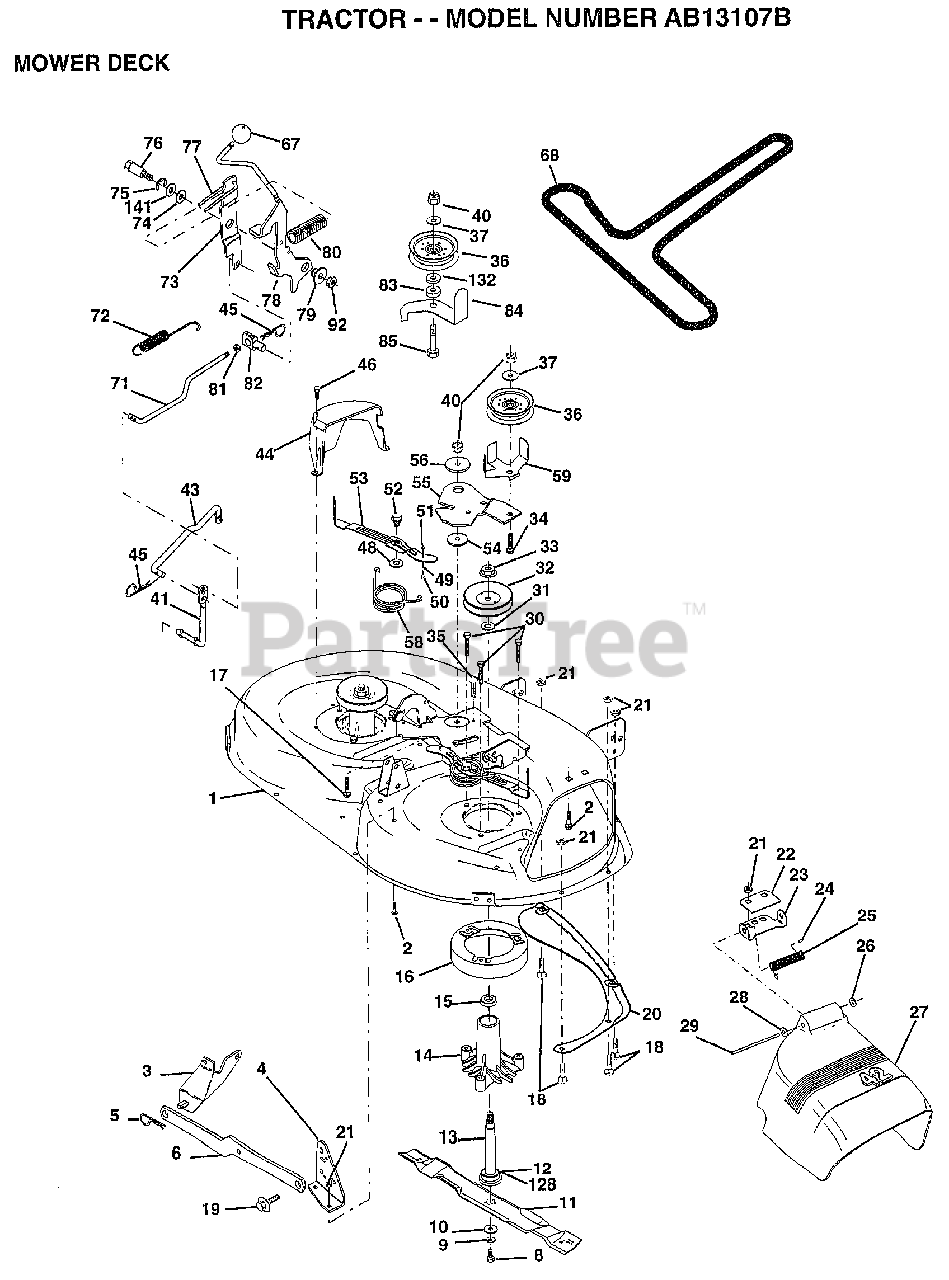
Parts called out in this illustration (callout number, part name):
1	"HOUSING ASSY.42"""
2	BOLT
3	BRKT ASM SWAY BAR
4	BRKT DECK SW BAR
8	BLADE BOLT
10	WASHER.HARD.BLADE
11	"BLADE.42"" HIPERF"
12	BEARING.BALL
14	HSG ASM MANDREL
15	BEARING
16	STRIPPER RND MWR
17	BOLT RDHD 3/8-16
18	BOLT
19	BOLT SHD 5/16-18
20	BAFFLE VORTEX 42
22	STIFFENER BRKT
23	DEFLECTOR BRKT
24	CAP-SLEEVE LT
25	SPRING TORSION
26	NUT PUSH M
27	DEFLECTOR.SHIELD
28	WASHER
29	HINGE ROD
30	"SCREW-THD ROLL,WA"
31	WASHER
32	PULLEY.MANDREL.42
34	BOLT
35	XMAS TREE FASTNER
36	FLAT IDLER PULLEY
37	WASHER
41	PIVOT ROD
43	ROD CLUTCH W/NIBS
44	GUARD MAND LH BLK
45	RETAINER M
46	SCREW.1/4-20X5/8
48	HARD SMALL WASHER
49	ROLLER ASM-CAM
50	SHOULDER BOLT
51	LOCKNUT
52	BOLT.SHLD.5/16-18
53	BRAKE PAD ARM ASM
54	HARDENED WASHER
55	ARM-IDLER
56	SPACER RETAINER
58	SPRING TORSN BRAK
59	GUARD IDLER TUV
67	KNOB.RD.7/16-14
68	BELT.V.T-PATH
71	ROD CLUTCH 38/42
72	RETURN SPRING
73	CLUTCH ARM SECOND
74	WASHER
75	RING
76	SHOULDER BOLT
77	SPRING KEEPER
78	LEVER.ASM.CLUTCH
79	BUSHING
80	SPRING.CLUTCH.MWR
81	NUT
82	TRUNION ADJ
83	WASHER
84	"KEEPER-BELT,FIXED"
85	BOLT
92	NUT
128	WASHER.FELT.
132	WASHER GT
141	WASHER .T
